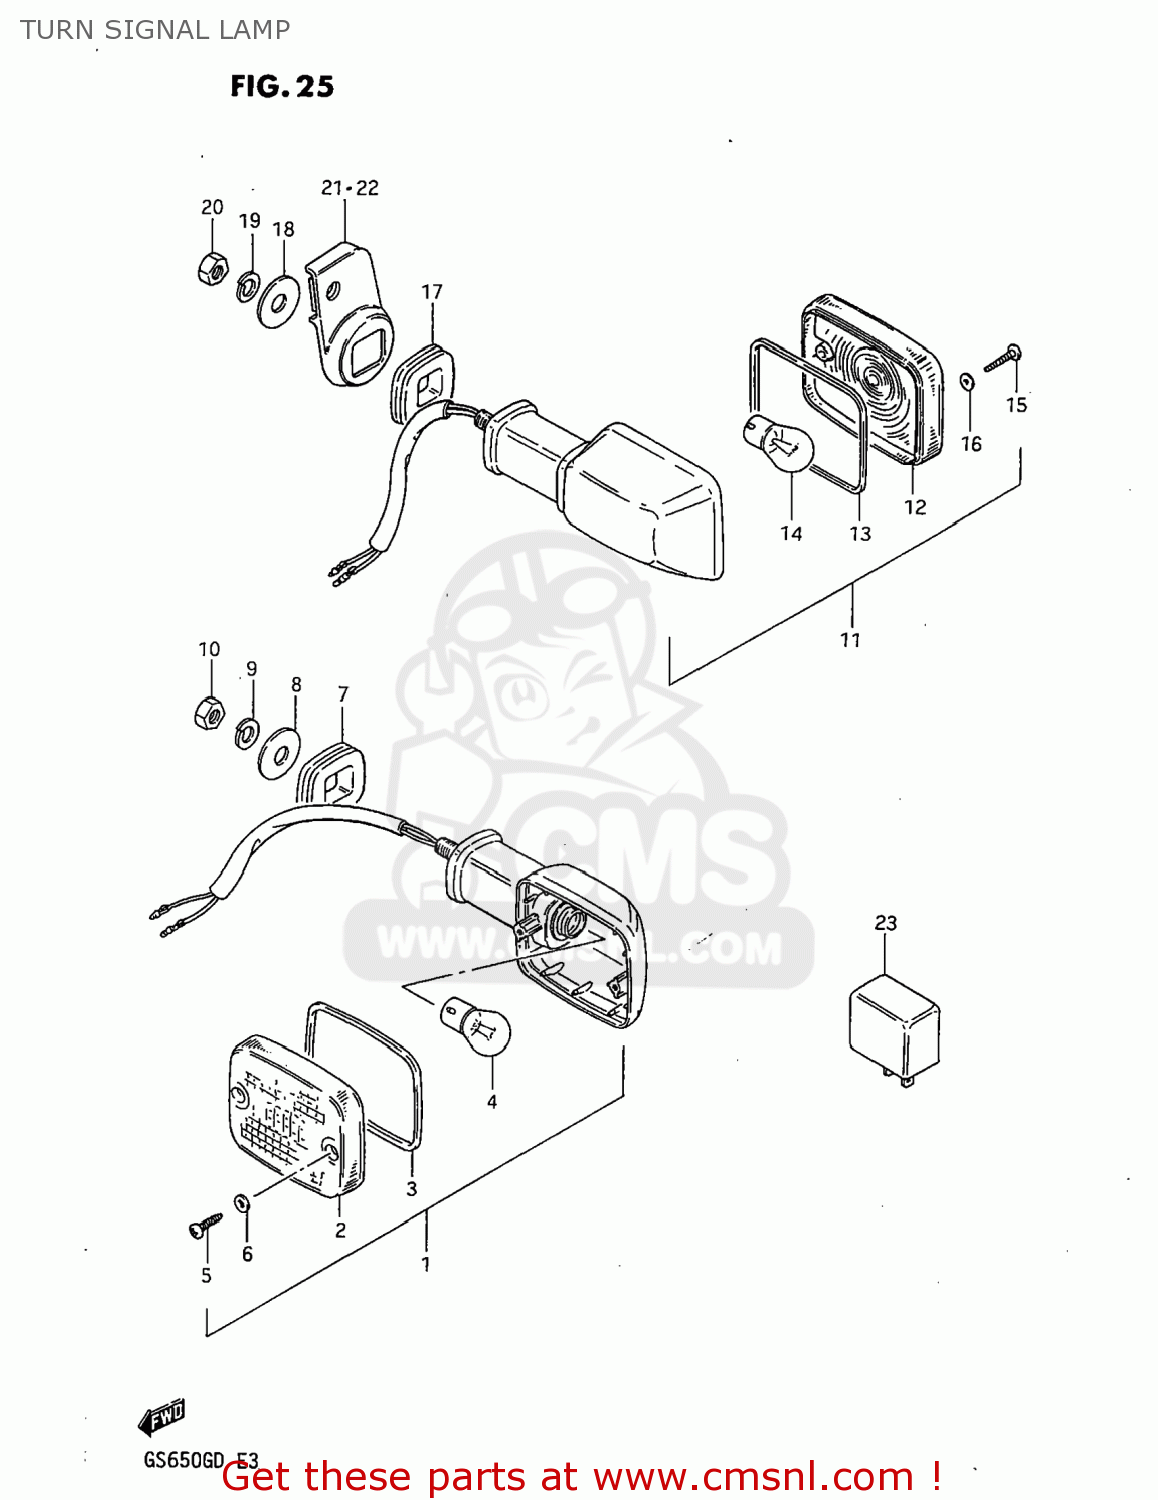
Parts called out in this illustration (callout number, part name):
1	LAMP ASSEMBLY,FRONT TURN SIGNAL
2	LENS
3	GASKET (NAS)
4	BULB(12V23W,STANLEY,A4577A)
5	SCREW
6	GASKET (NAS)
7	CUSHION
8	WASHER (10.5X30X2.3)
9	LOCK WASHER
10	NUT
11	LAMP ASSEMBLY,FRONT TURN SIGNAL
12	LENS
13	GASKET (NAS)
14	BULB(12V23W,STANLEY,A4577A)
15	SCREW
16	GASKET (NAS)
17	CUSHION
18	WASHER (10.5X30X2.3)
19	LOCK WASHER
20	NUT
21	BRACKET,REAR TURN SIGNAL
22	BRACKET,REAR TURN SIGNAL
23	RELAY,TURN SIGNAL
